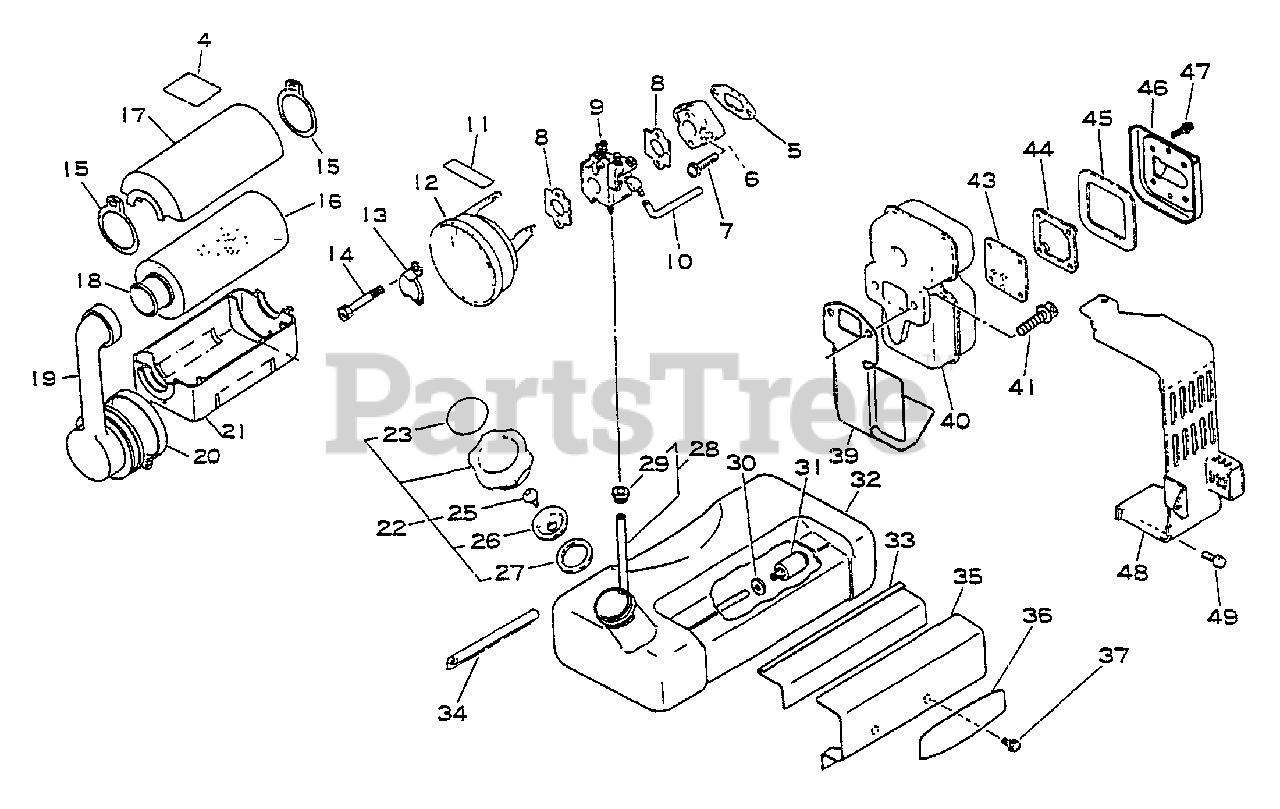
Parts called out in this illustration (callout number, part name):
4	LABEL - CAUTION
5	GASKET, INTAKE
6	INSULATOR
7	SCREW 6×25
8	GASKET, INTAKE
9	CARBURETOR - WA-55B
10	PIPE
11	LABEL - CHOKE
12	CASE, AIR FILTER
13	PLATE, PREVENT
14	BOLT
16	FILTER, AIR
17	COVER, AIR FILTER
18	HOLDER, AIR FILTER
19	ADAPTER, INTAKE
21	CASE, AIR FILTER
22	CAP ASSY
23	LABEL - FUEL MIX
25	VALVE, CHECK
26	HOLDER, VENT
27	GASKET
28	PIPE, FUEL W/GROMMET 3×5×250L
30	WASHER 5.5×12×0.8
31	FILTER, FUEL
32	TANK, FUEL
33	CUSHION, FUEL TANK
34	CUSHION, FUEL TANK
35	BRACKET, FUEL TANK
36	LABEL - ECHO
37	SCREW 5×10
39	GASKET, EXHAUST
41	BOLT 6×20
43	SCREEN KIT
44	SEAT, SCREEN
45	GASKET, EXHAUST
46	GUIDE, EXHAUST
47	SCREW 4×14
48	COVER, EXHAUST
49	SCREW 5×14
